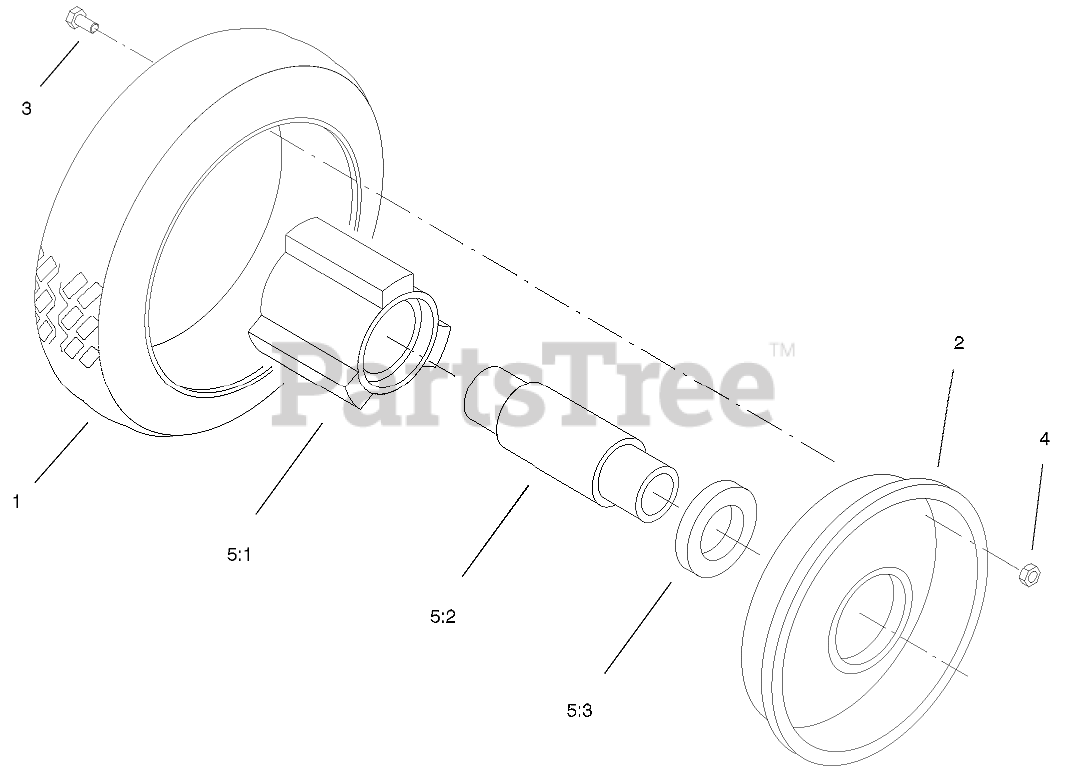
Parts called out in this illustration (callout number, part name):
2	PLATE-WHEEL, HALF
3	SCREW-HH
4	NUT-LOCK, NI
5	Hub and Bearing ASM
5:1	HUB-BEARING
5:2	SPACER-BEARING
5:3	BEARING-WHEEL
